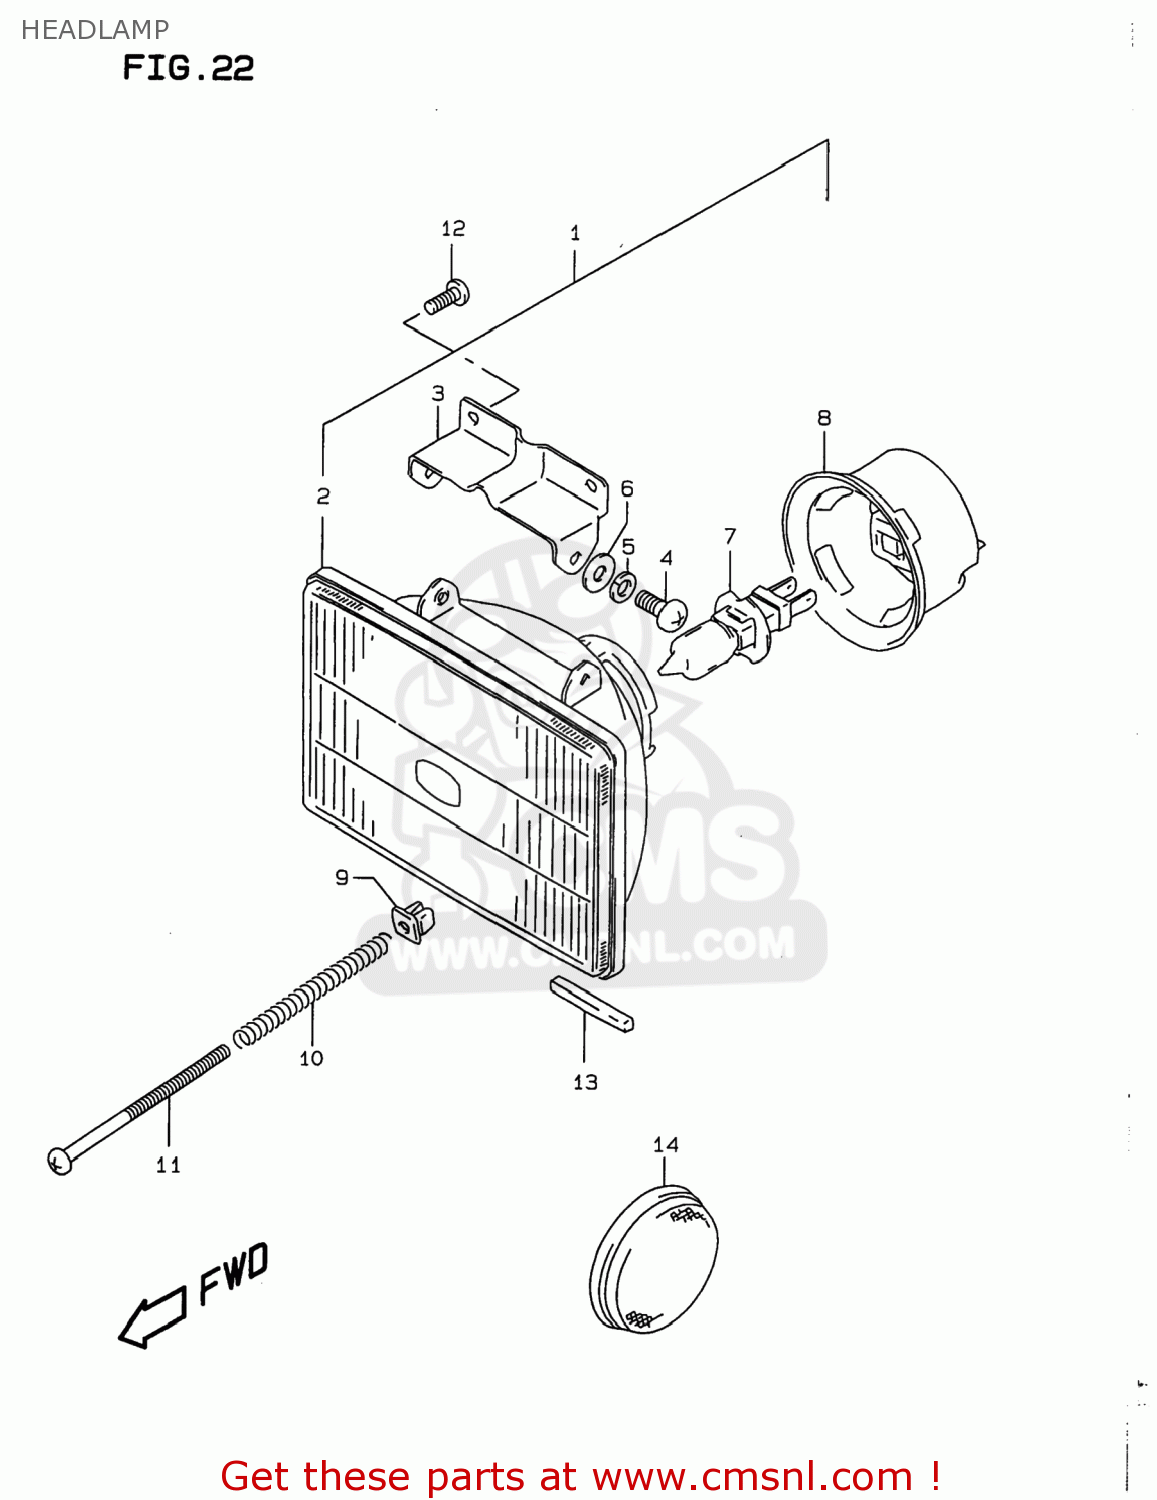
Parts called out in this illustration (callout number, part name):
1	HEADLAMP ASSY
2	UNIT,LAMP
3	BRACKET,LAMP
4	SCREW
5	WASHER,LOCK
6	WASHER
7	BULB(12V55W)
8	COVER,SOCKET
9	NUT,ADJUSTING
10	SPRING,HEAD LAMP ADJUSTER
11	SCREW(4X45)
12	SCREW
13	PROTECTOR(50X50X5)
14	REFLECTOR,REFLEX FR
